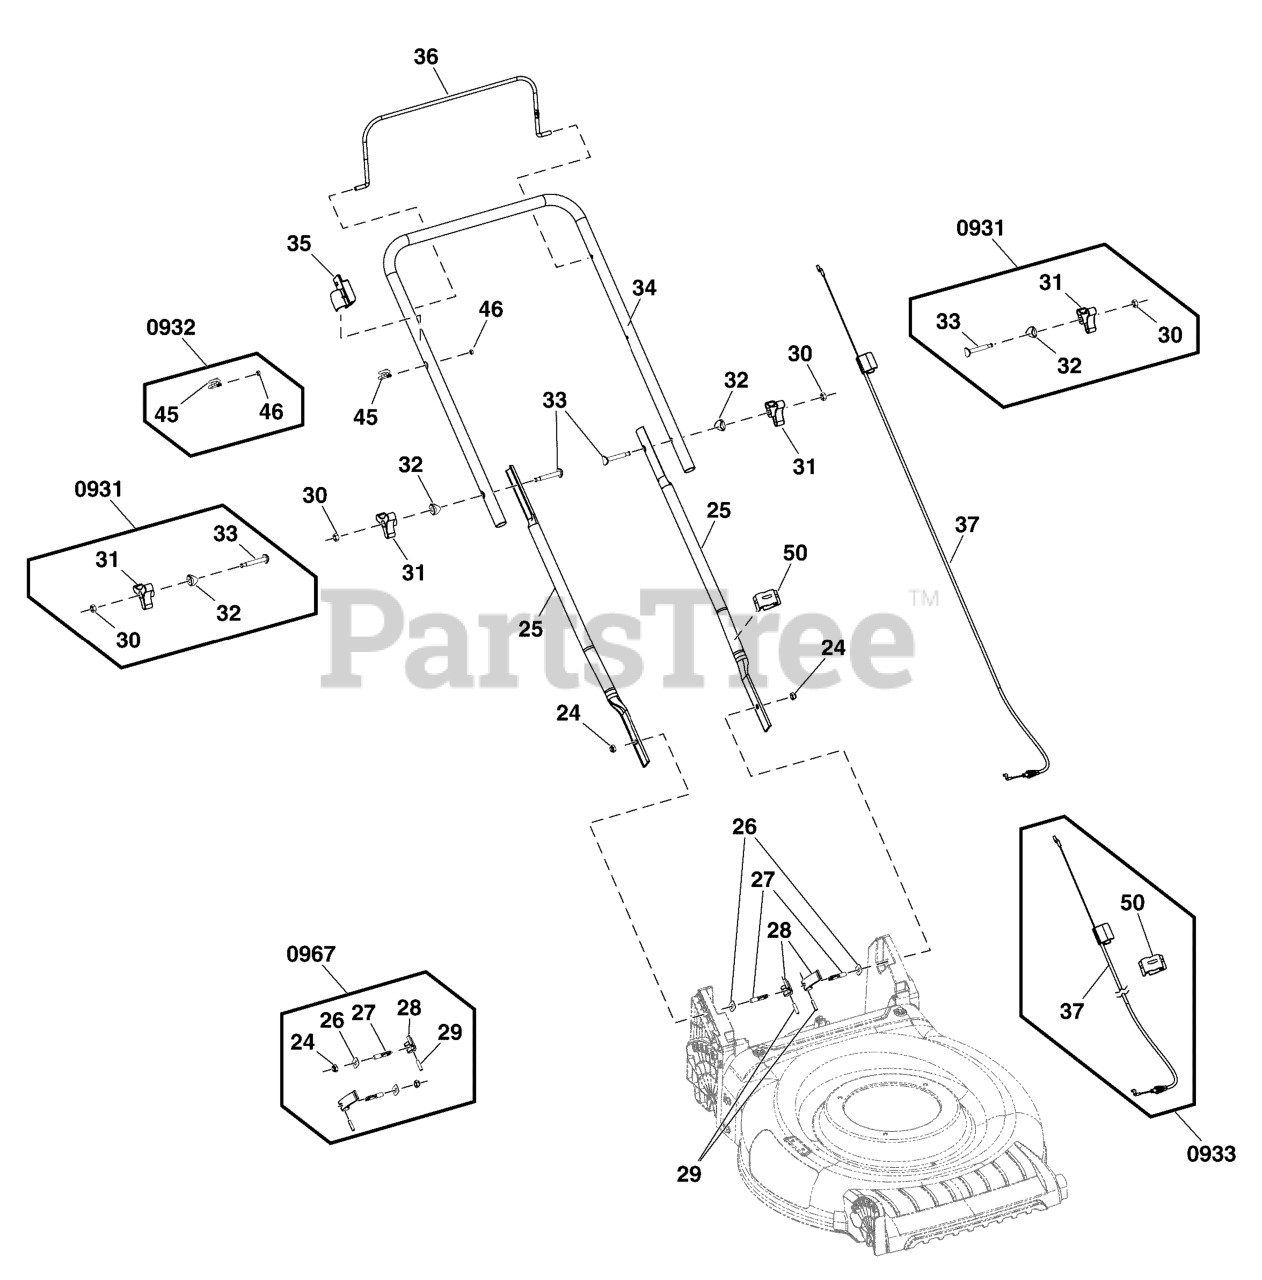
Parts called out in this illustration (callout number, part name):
24	NUT, Lock
25	HANDLE, Lower
26	PLATE, Compression
27	BOLT, Locking Handle
28	CAM, Handle
29	PIN
30	NUT
31	KNOB, Wing
32	WASHER, Curved
33	BOLT, Carriage
34	HANDLE, Upper
35	BRACKET, Rod
36	BAIL ASSEMBLY
37	CABLE, Engine Stop
45	GUIDE, Rope
46	NUT, Lock
50	CLIP, Cable
0931	KIT, Wing Knob, Handle
0932	KIT, Rope Guide
0933	KIT, Cable, Engine Stop
0967	KIT, Knob, Lever
